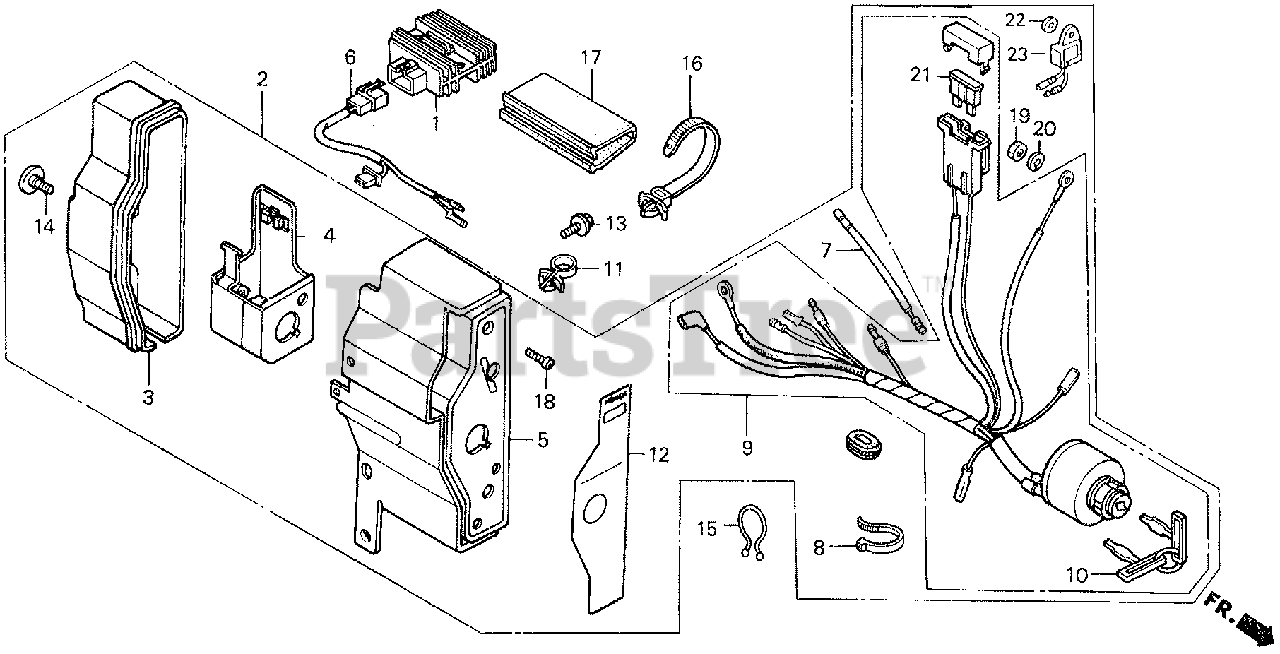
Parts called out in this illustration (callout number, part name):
1	RECTIFIER ASSY., REGULATOR
2	BOX ASSY., CONTROL (EXTERNAL-ALERT/10A) *R8* (BRIGHT RED)
3	CASE, CONTROL
4	BRACKET, CASE MOUNTING
5	PANEL, CONTROL *R8* (BRIGHT RED)
6	SUB-WIRE HARNESS ASSY.
7	SUB-HARNESS
8	BAND
9	SWITCH ASSY., COMBINATION
10	KEY
11	HOLDER, STOP SWITCH WIRE
12	MARK, CONTROL BOX (EXTERNAL-REGULATOR)
13	BOLT, FLANGE (6X12) (CT200)
14	SCREW, SPECIAL (6X12)
15	CLIP, PURSE LOCK
16	STRAP, CABLE (118MM) *NH1L* (BLACK)
17	TUBE, FASTENER (30)
18	SCREW, PAN (4X12)
19	NUT, HEX. (4MM)
20	WASHER, SPRING (4MM)
21	FUSE, BLADE (15A)
22	WASHER, PLAIN (4MM)
23	ALERT UNIT, OIL
